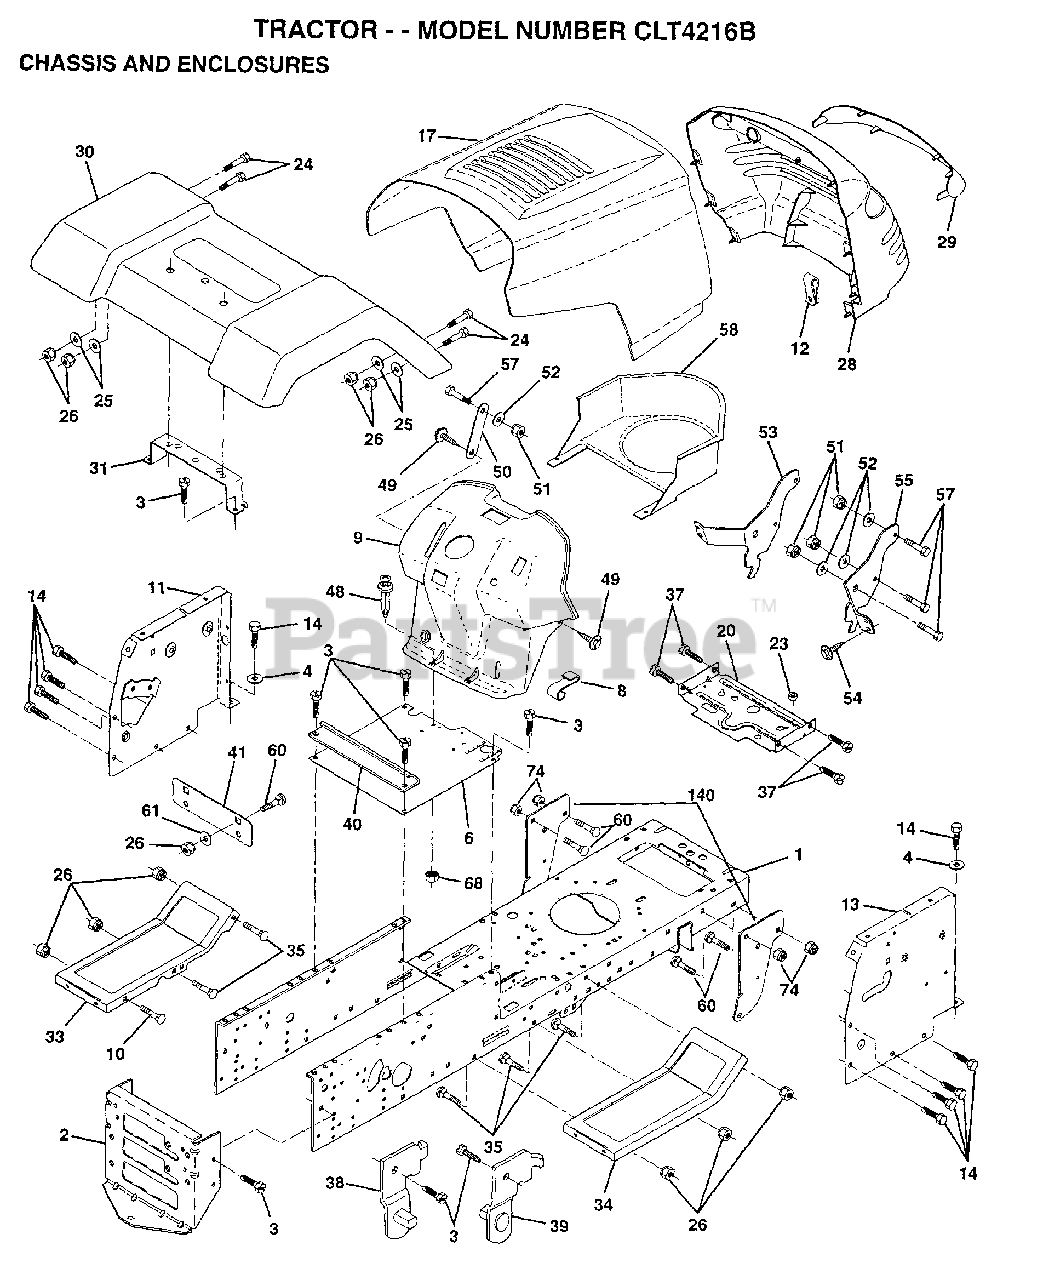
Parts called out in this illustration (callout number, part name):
1	CHASSIS WLDMT 11G
3	SCREW
4	WASHER
8	"CLIP,INSULATOR"
11	PANEL.DASH.LH.
12	CLIP.TINNERMAN
13	PANEL.DASH.RH
14	SCREW LT
20	PLATE.MTG.BTRY.TK
24	BOLT
25	WASHER
26	NUT
28	GRILL QUADRA
29	LENS QUADRA
31	BRACKET SUPT FEND
33	FOOTREST.LH.LT/GT
34	FOOTREST.RH.LT/GT
35	BOLT
37	SCREW LT
38	BRACKET ASM LH
39	BRACKET ASM RH
40	SPACER FENDER LT
41	PLATE EXTEN FEND
48	RIVET.PUSH.PLATE
49	SCREW HEX CRT
50	BRACE SUPT DASH
51	NUT
52	WASHER
53	BRACKET.GRILLE.LH
55	BRACKET.GRILLE.RH
58	DUCT.AIR.B&S.18HP
60	BOLT
61	WASHER
68	NUT
